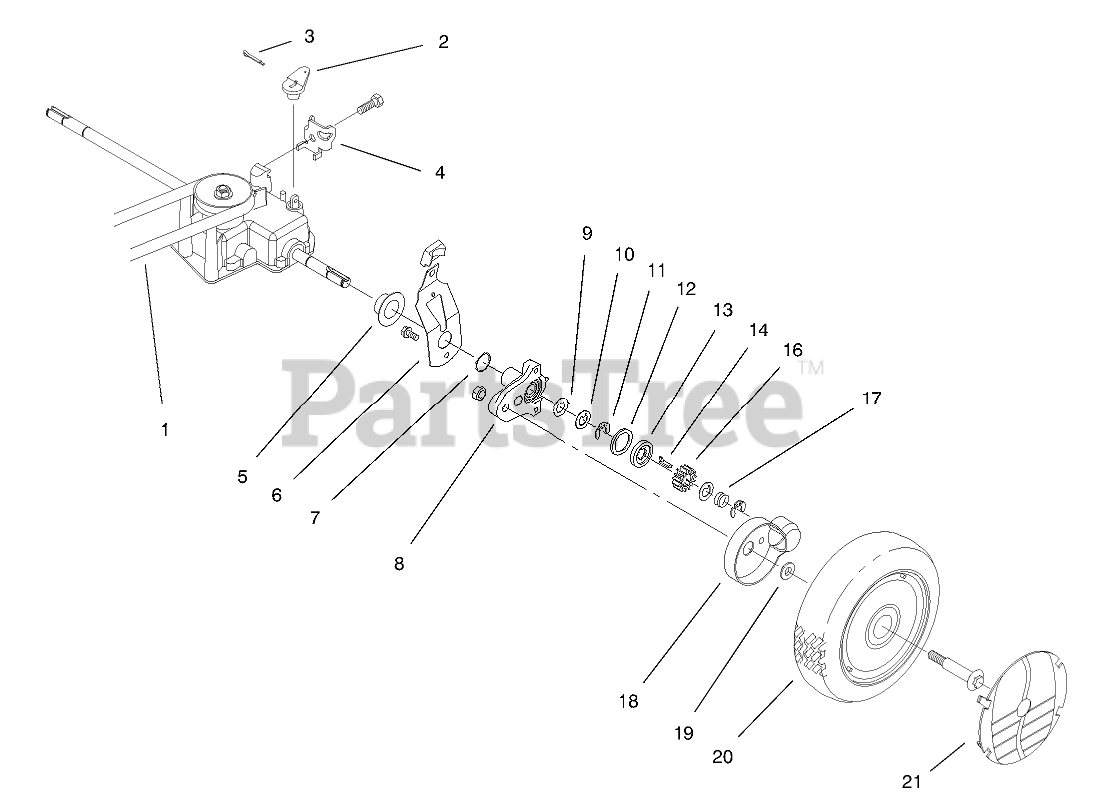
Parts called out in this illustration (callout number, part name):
1	V-BELT E
2	LEVER-SHIFT
3	PIN-COTTER
4	CLAMP-CABLE
5	CAP-END
6	SPRING ARM ASM
7	O-RING
8	PIVOT ARM ASM
9	WASHER-ARM, PIVOT
10	WASHER-THRUST, KEYED
11	RING-CLIP, LOCKING
12	RING-FRICTION
13	WASHER-CLUTCH
14	KEY-ROCKING, LH
16	GEAR-PINION
17	SPRING-COMPRESSION
18	COVER-WHEEL
19	SPACER-COVER, WHEEL
20	WHEEL AND TIRE ASM (W/GEAR)
21	WHEEL COVER
